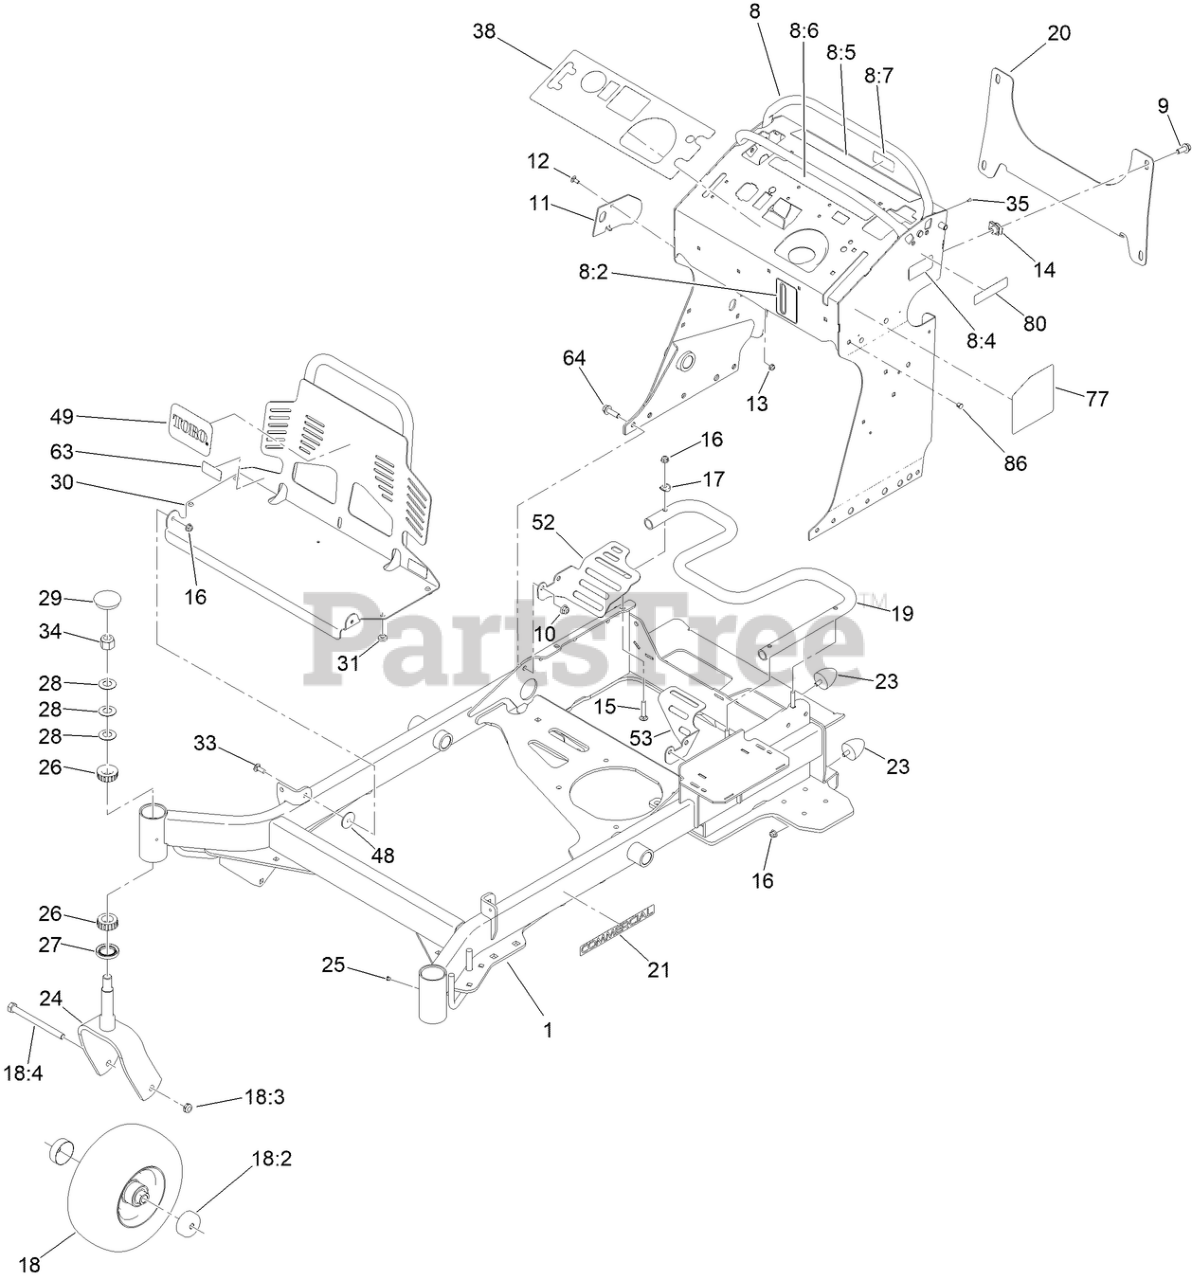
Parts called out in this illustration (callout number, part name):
8	TOWER DECAL ASM
8:2	DECAL-LEVEL, OIL
8:4	DECAL-FILL, FUEL
8:5	DECAL-WARNING
8:6	DECAL-CONTROLS
8:7	DECAL-FUSE
9	SCREW-HHF
10	NUT-HF, NI
11	PLATE-STRIKER
12	SCREW-CARR
13	NUT-HF
14	NUT-TINNERMAN
15	BOLT-CAR
16	NUT-HF, NI
17	WASHER
18	WHEEL, TIRE AND BEARING ASM
18:2	GUARD-SEAL
18:3	NUT-HEX
18:4	SCREW-HH
19	TUBE-MOUNT, FUEL TANK
20	BRACKET-CROSS
21	DECAL-COMMERCIAL
23	BUMPER-RUBBER
24	FORK-CASTER
26	BEARING-ROLLER, TAPERED
27	SEAL-GREASE
28	WASHER-BELLVILLE
29	CAP-GREASE
30	GUARD-ENGINE
31	BUMPER
33	BOLT-CARR
34	NUT-LOCK, NI
35	RIVET-POP
38	DECAL-PANEL, CONTROL
48	WASHER-NYLON
52	GUARD-FAN, RH
53	GUARD-FAN, LH
63	DECAL-WARNING, NO RIDERS
64	SCREW-HHF
77	DECAL-SERVICE AID
80	DECAL-ARRESTOR, SPARK
86	DOME PANEL PLUG
